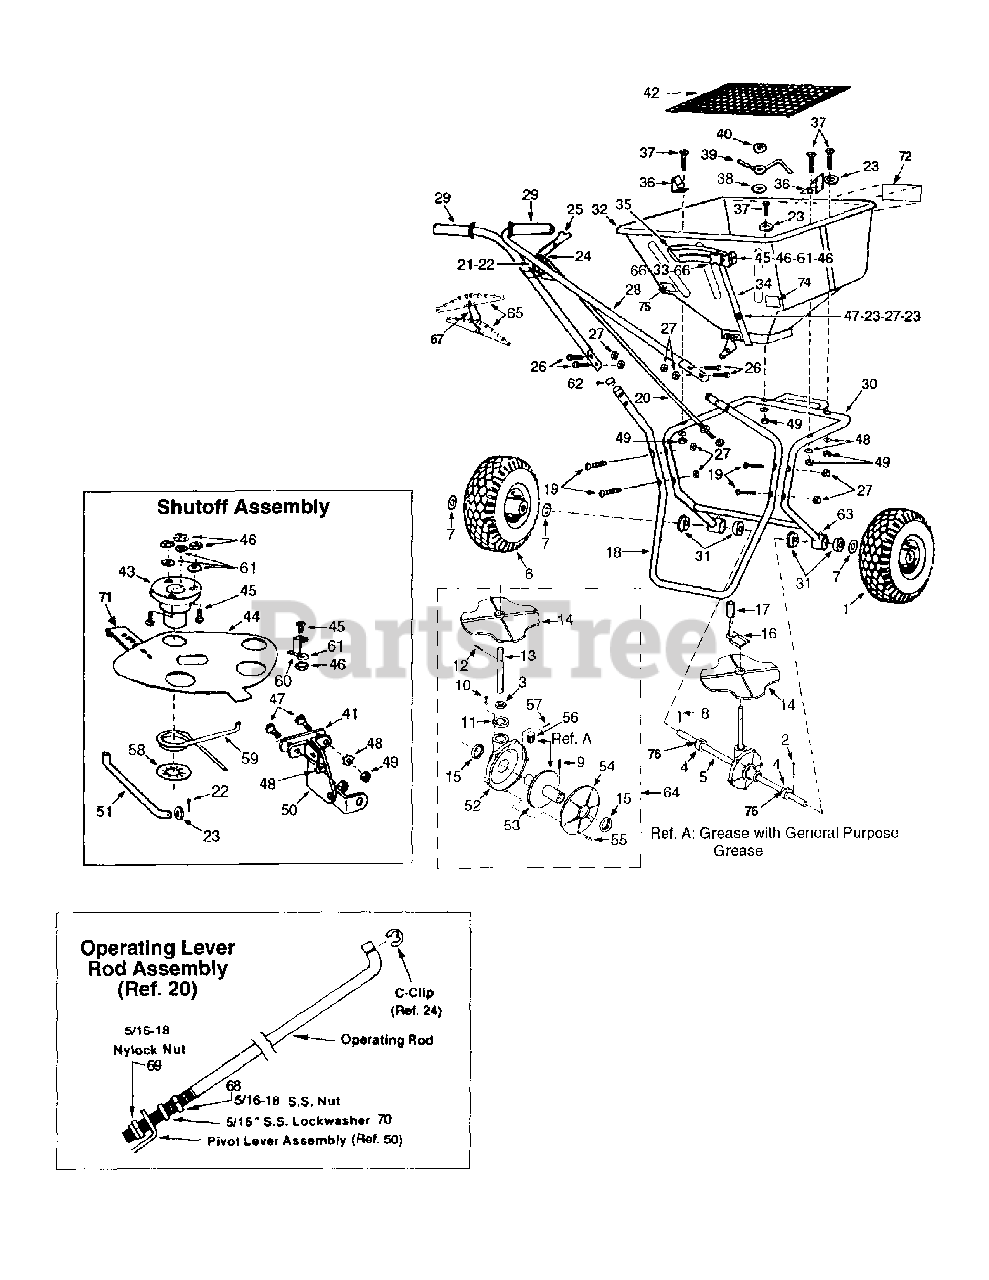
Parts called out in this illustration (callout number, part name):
1	Drive Wheel, Composite
2	Cotter Pin, 3/16 x 1-3/4, SS
3	Seal, Gear Set Cap
4	Shaft Collar, SS
5	Spreader Axle, SS
6	Idler Wheel, Composite
7	Spacer Washer, SS
9	Roll Pin, 5/32 x 1-/14, SS
10	Screw, #10 x 5/8 T-A Hex Slot Hd., SS
11	Cap, Gear Set
12	Roll Pin, 1/8 x 7/8, SS
13	Impeller Shaft, SS
14	Impeller
15	Seal, Housing and Cover
16	Agitator Arm and Shaft Assembly
17	Bearing, Agitator Shaft
18	Leg, Epoxy Finish
18	Leg, Stainless Steel
19	Mach.Screw,1/4-20 x 2 Pan Phil. Hd., SS
20	Operating Lever Rod
21	Clevis Pin, 1/4 x 1/2, SS
22	Cotter Pin, 3/32 x 1/2, SS
23	Flat Washer 1/4" SAE, SS
24	C-Clip
25	Operating Lever and Rubber Handle
26	Cap Screw 1/4-20 x 1-1/4 Hex Hd., SS
27	Hex Nut 1/4-20 Nylock, SS
28	Handle, Epoxy Finish
28	Handle, Stainless Steel
29	Flanged Grip, Black, 3/4 x 4
30	Uni-Frame, Epoxy Finish
30	Uni-Frame, Stainless Steel
31	Axle Bushing, Composite
32	Hopper
33	Rate Control Knob
34	Rate Control Arm
35	Rate Control Plate
36	Screen Clip, SS
37	Mach. Screw, 1/4-20 x 1-1/2 Rd. Phil. Hd., SS
38	Flat Washer, 3/8 Nylon
39	Agitator Arm
40	Spring Clip
41	Plate, Two-Hole, Weldment
42	Screen
43	Shaft Support, Impeller
44	Shutoff Plate
44	Box
45	Mach. Screw, #8-32 x 112 Pan Phil. Hd., SS
46	Hex Nut, #8-32, SS
47	Mach. Screw, 1/4-20 x 718 Pan Phil. Hd.,SS
48	Lock Washer, 1/4, SS
49	Hex Nut, 1/4-20, SS
50	Pivot Lever Assembly
51	Pivot Lever Rod
52	Housing, Gear Set
53	Gear
54	Cover, Gear Set
55	Screw, #6 x 5/8, SS
56	Pinion Gear
57	Roll Pin, 1/8 x 5/8, SS
58	Spring Clip 3/4, SS
59	Rate Control Spring
60	Shutoff Plate Clip
61	Lock Washer #8 Star, SS
62	Plug, Plastic (Epoxy Frame)
62	Plug, Plastic (Stainless Frame)
63	Grease Fitting, 1/4-28 Straight
64	Kit, Impeller and Gear Set
65	Calibration Gauges (Odd)
65	Calibration Gauge (Even)
66	Nylon Washer
67	Chain
68	Hex Nut
69	Nylock Nut
70	Locking Washer
71	Slide Plate
72	MTD Decal
73	Parts List and Instructions
74	80 lb. Capacity Decal
75	USA Decal
76	Set Screw
